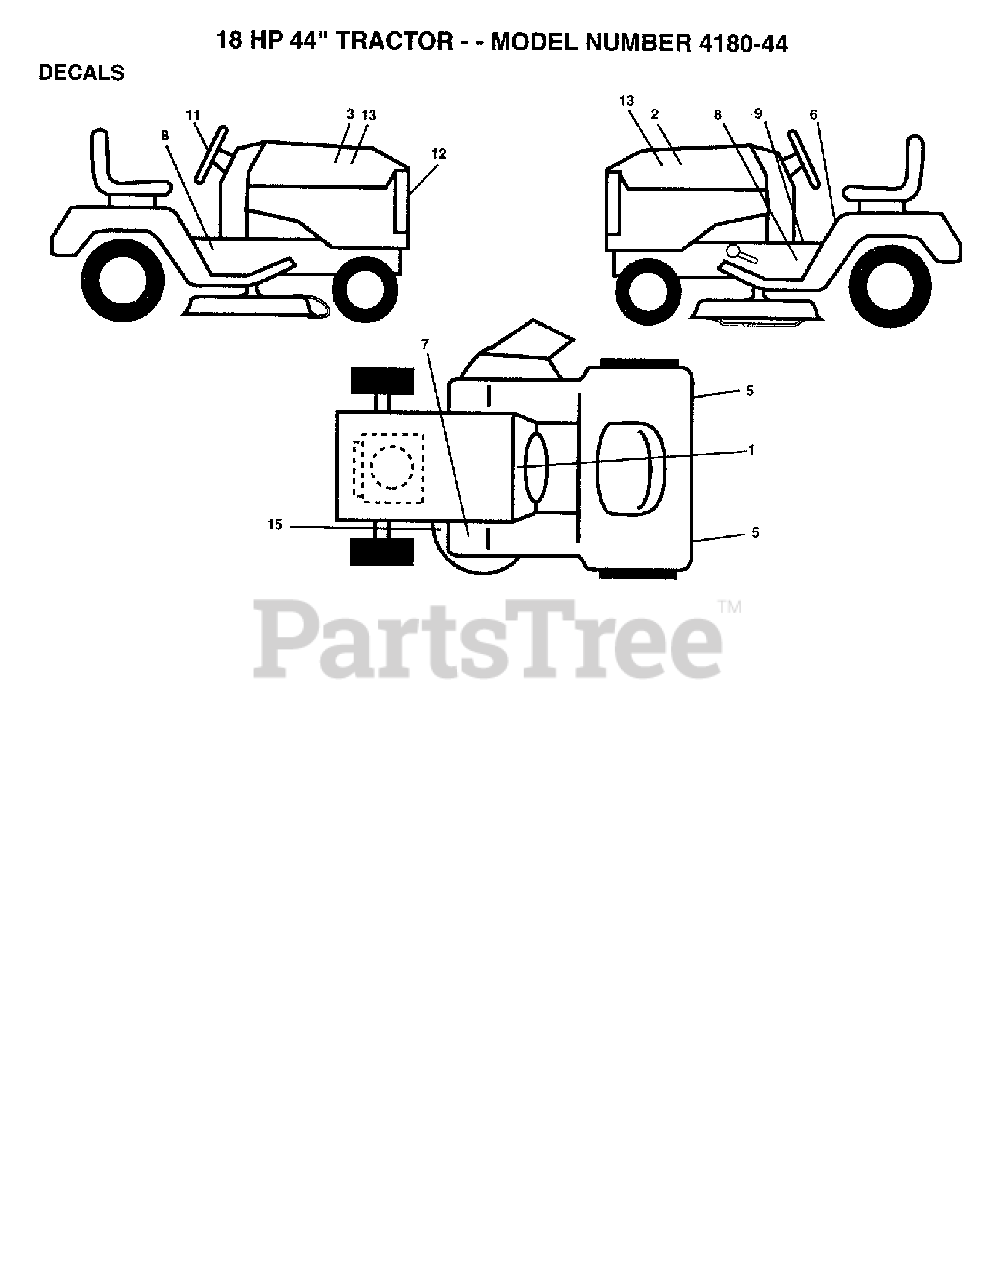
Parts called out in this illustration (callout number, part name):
2	Poulan TBD
3	Poulan TBD
5	REFLECTOR-TAIL YT
6	DECAL LT
8	Poulan TBD
9	DECAL PARK BRAKE
11	Poulan TBD
12	Poulan TBD
13	Poulan TBD
